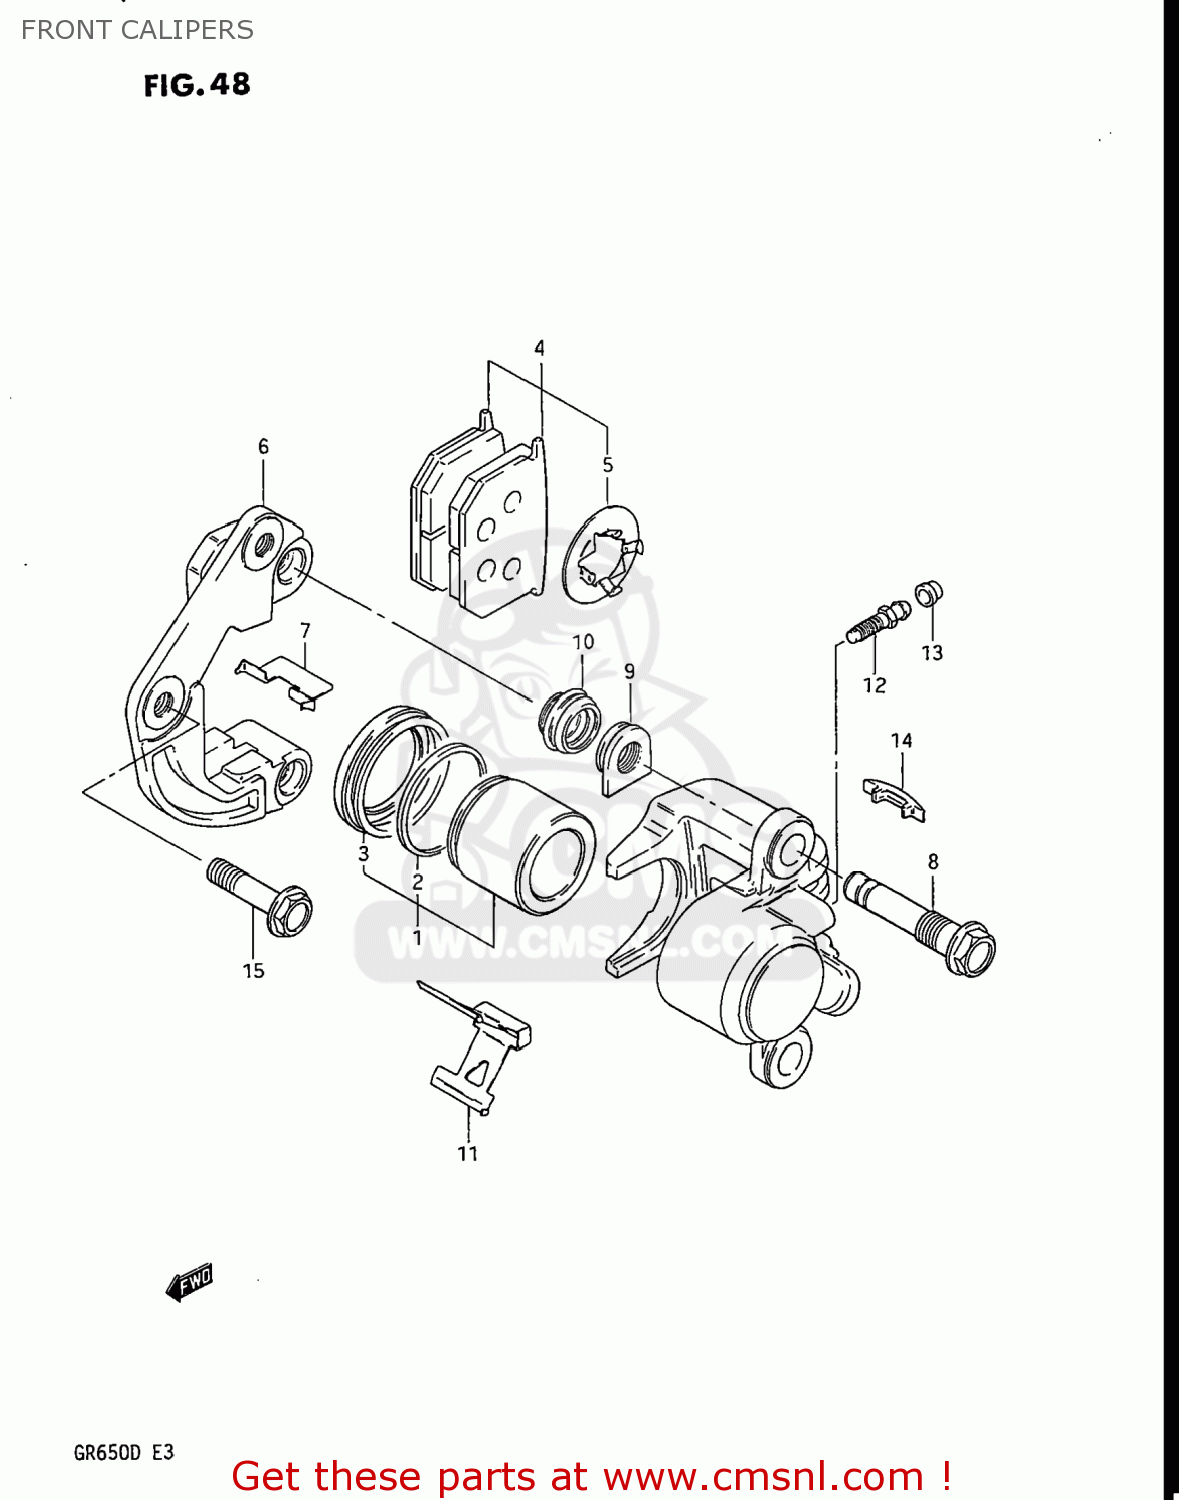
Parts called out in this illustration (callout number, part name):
1	PISTON SET
2	SEAL,PISTON
3	BOOT,PISTON
4	PAD & SHIM SET (NAS)
5	SHIM,PAD
6	HOLDER,CALIPER,LEFT
7	PAD,GUIDE
8	AXLE
9	NUT,CALIPER AXLE
10	BOOT
11	SPRING
12	BREATHER
13	CAP,BLEEDER PL
14	COVER,INDICATOR
15	BOLT(10X37)
